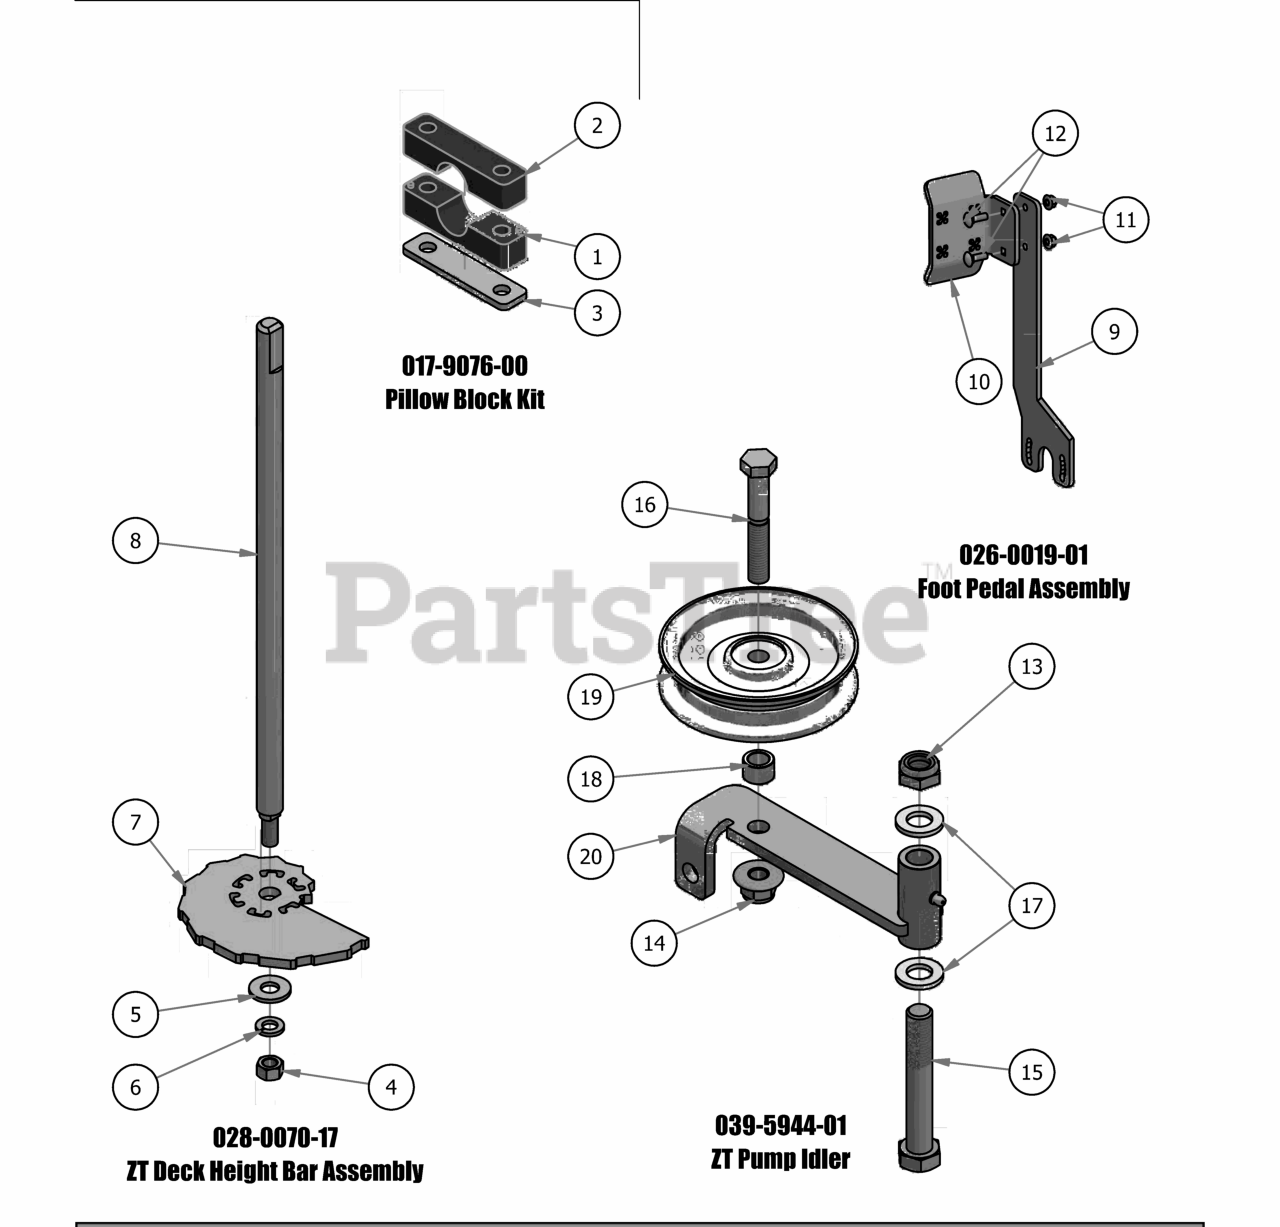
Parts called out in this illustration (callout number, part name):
1	Pillow Block MZ male
2	Pillow Block MZ female
3	Pillow Block Strap
4	3/8" Fine Threaded Jam Nut
5	3/8" Flat Washer
6	3/8" Lock Washer
7	2017 MZ/ZT Cam Plate
8	2017 Deck Height Dial Rod ZT
9	2017 MZ/ZT Deck Pedal Lever
10	2017 MZ/ZT Shallow Foot Pedal
11	5/16" Nylon Flange Nut
12	5/16" x 1" Carriage Bolt
13	5/8" Nylock (1/2 Jam)
14	1/2-13 Nylon Flange Nut
15	5/8" x 4" Hex Bolt
16	1/2 x 2-3/4 Hex Bolt
17	.630 ID Plastic Washer
18	1/2 x 1/2 Spacer
19	4 3/4" Idler Pulley
20	Pump Idler Bracket
